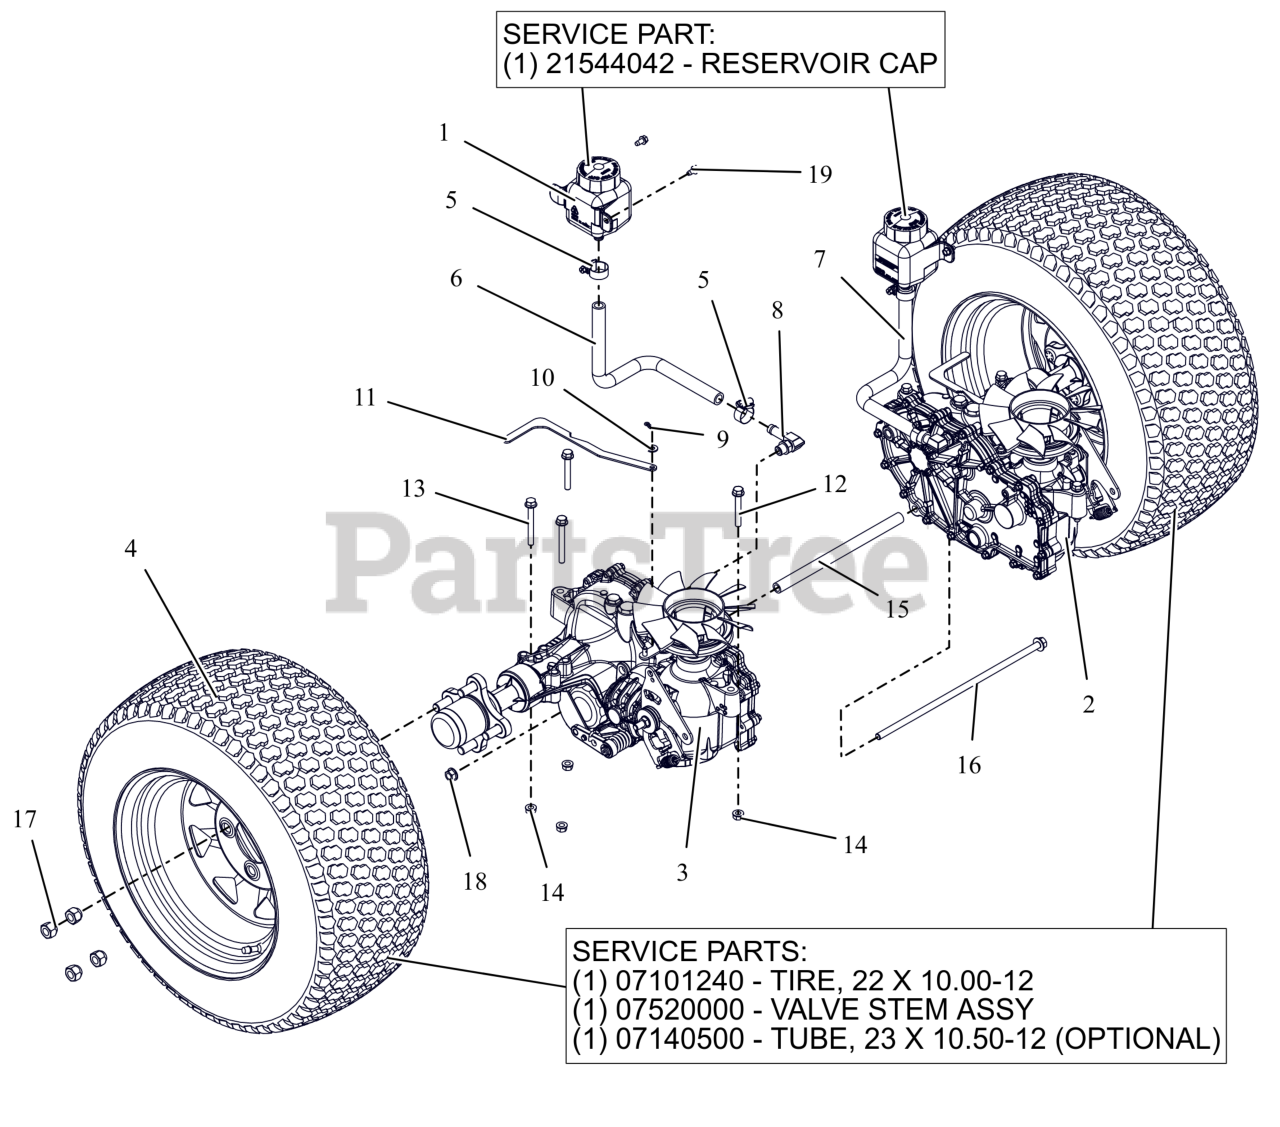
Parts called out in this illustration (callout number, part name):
1	TANK, EXPANSION
1	CAP, HYDRO RESERVOIR REPLAC.
2	TRANSAXLE, ZT3200 - LH
3	TRANSAXLE, ZT3200 - RH
4	ASM, WHL/TIRE 22X10-12 LG BLK
4	TIRE, 22X10.00-12
4	VALVE STEM ASS'Y
4	TUBE 22,23&24X8.50/9.50/10.00/10.50/12.00-12
5	CLAMP,.88 DIA. HOSE
6	HOSE, FORMED EXPANSION -HD RH
7	HOSE, FORMED EXPANSION -HD LH
8	FITTING, HYD (90 DEG)
9	PIN, HAIR #225 .072X1.09
10	WSHR,FLT .281X.625X.065 ZCC
11	BRKT, VALVE DUM
12	BLT,HEX-FLG .31-18X2.25 G5 ZCC
13	BLT,HEX-FLG .31-18X2.75 G5 ZCC
14	NUT,LK-CTR-FLG .31-18 GF ZCC
15	SPCR, TRANSAXLE .406 ID X .630 OD X 9.95LG (BLACK)
16	BLT, HEX-FLG 0.375-16X13 GR5 ZC120
17	NUT, WHEEL .50-20 ZCC
18	NUT-LK-TOP-FLG .38-16 ZC120
19	SCR-TAP .25-20X.50 HWH ZCC
